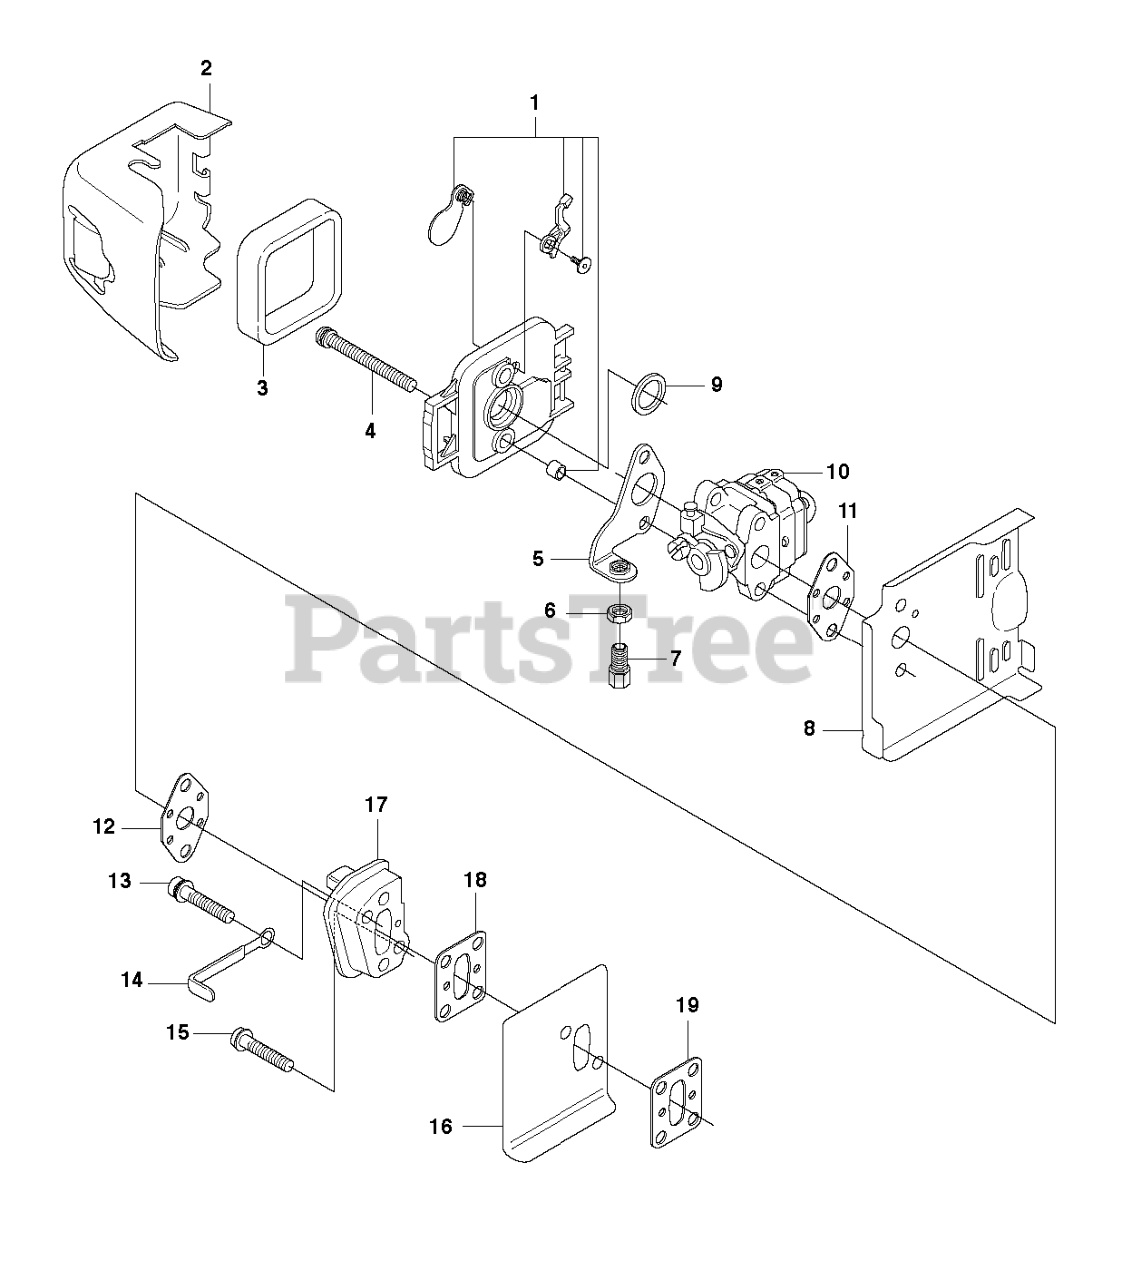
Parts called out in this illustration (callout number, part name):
1	FILTER COVER
3	FILTER ELEMENT
10	CARBURETOR
